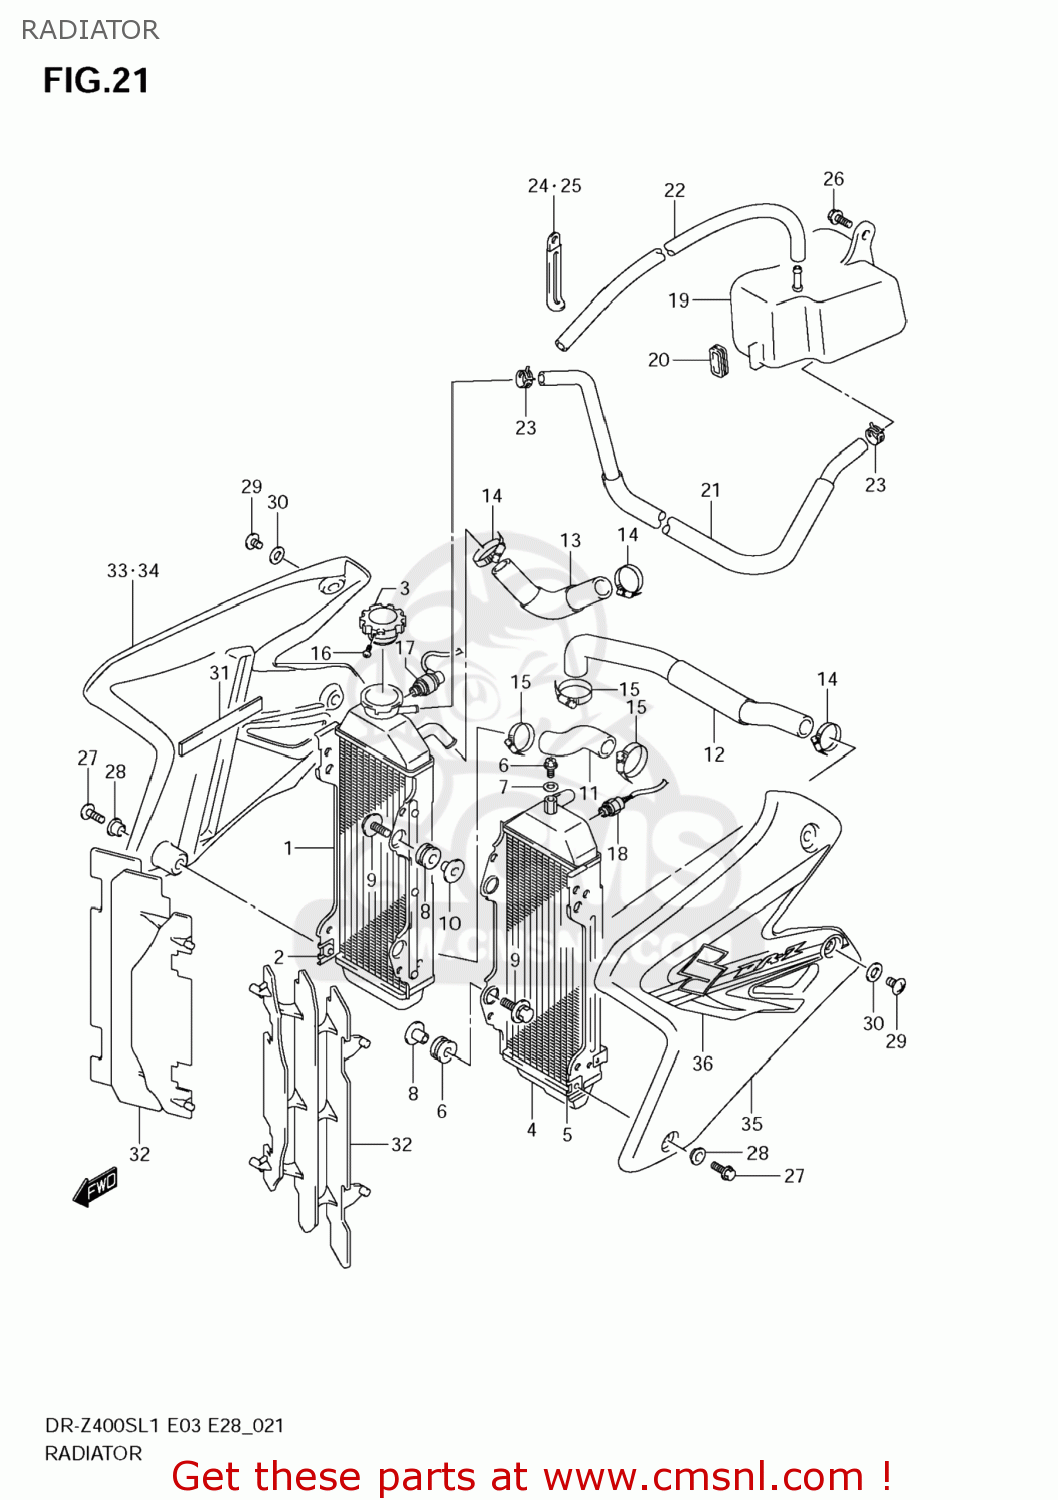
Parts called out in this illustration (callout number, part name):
1	RADIATOR,WATER,R
2	NUT
3	CAP,RADIATOR(1.1)
4	RADIATOR,WATER,L
5	NUT
6	UNION BOLT,AIR VENT
7	GASKET(6.4X11.5X0.8) (NAS)
8	CUSHION,RADIATOR LWR
9	BOLT(6X25)
10	SPACER(6.5X10.5X14.1)
11	HOSE,RADIATOR INLET
12	HOSE,RADIATOR OUTLET
13	HOSE,RADIATOR JOINT
14	CLAMP
15	CLAMP
16	SCREW,RADIATOR CAP
17	SWITCH ASSY,WATER TEMP
18	SWITCH,FAN
19	TANK,RESERVOIR
20	CUSHION,RESERVOIR TANK
21	HOSE,RESERVOIR TANK INLET
22	HOSE(5X9X2000)
23	CLIP
24	CLAMP(L:45 T:0.6)
25	CLAMP(L:45)
26	BOLT
27	BOLT(6X16)
28	WASHER
29	BOLT(6X8)
30	WASHER(6.5X14X1.6)
31	CUSHION,TOOL HOLDER
32	LOUVER,RADIATOR
33	COVER,RADIATOR,R(BLACK)
34	TAPE,RADIATOR COVER,R
35	COVER,RADIATOR,L(BLACK)
36	TAPE,RADIATOR COVER,L
